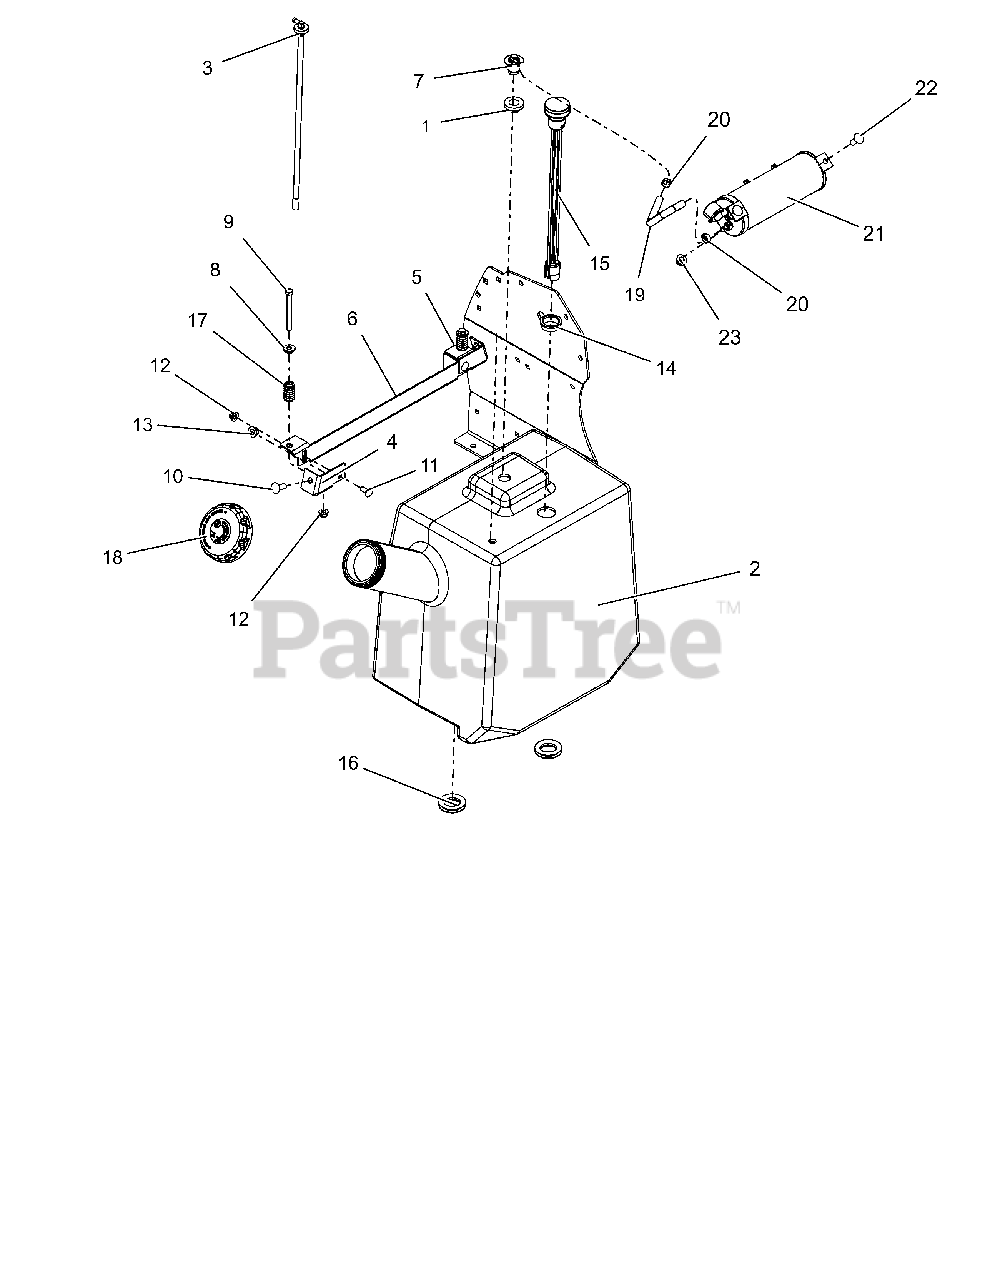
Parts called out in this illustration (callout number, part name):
1	GROMMET, REMOTE VENT NITRILE
2	TANK, PROSTANCE FUEL
3	ASS'Y, PROSTANCE FUEL PICK-UP
4	MOUNT, FUEL TANK HOLD DOWN-RH
5	MOUNT, FUEL TANK HOLD DOWN-LH
6	HOLDDOWN, FUEL TANK
7	VALVE, 2-WAY
8	BSHG-FLG .32X.500X.344X.880
9	@BLT-HEX .31-18X3.25 GR5 YWZC
10	@BLT-RDHDSHSQNK.38-16X1.0 G5YZ
11	@BLT-RDHDSQNK .31-18X.75 G5YZ
12	@NUT-LK-NYL-FLG .31-18 YWZC
13	@NUT-LK-NYL-FLG .38-16 YWZC
14	GROMMET, FUEL GAUGE
15	GAUGE, REMOTE FUEL SEALED 15"
16	GROMMET 1.25ID X 1.5OD
17	SG-COMP .125X.781X1.250
18	CAP, FUEL NONVENT AUTOLOCK
19	HOSE, .25 LOW-PERM BULK GAS
20	CLAMP, FUEL LINE
21	CANISTER, CARBON 9.3G CAP.
22	@BLT-RDHDSQNK .38-16X1.00 G5YZ
23	@NUT-LK-NYL-FLG .38-16 YWZC
